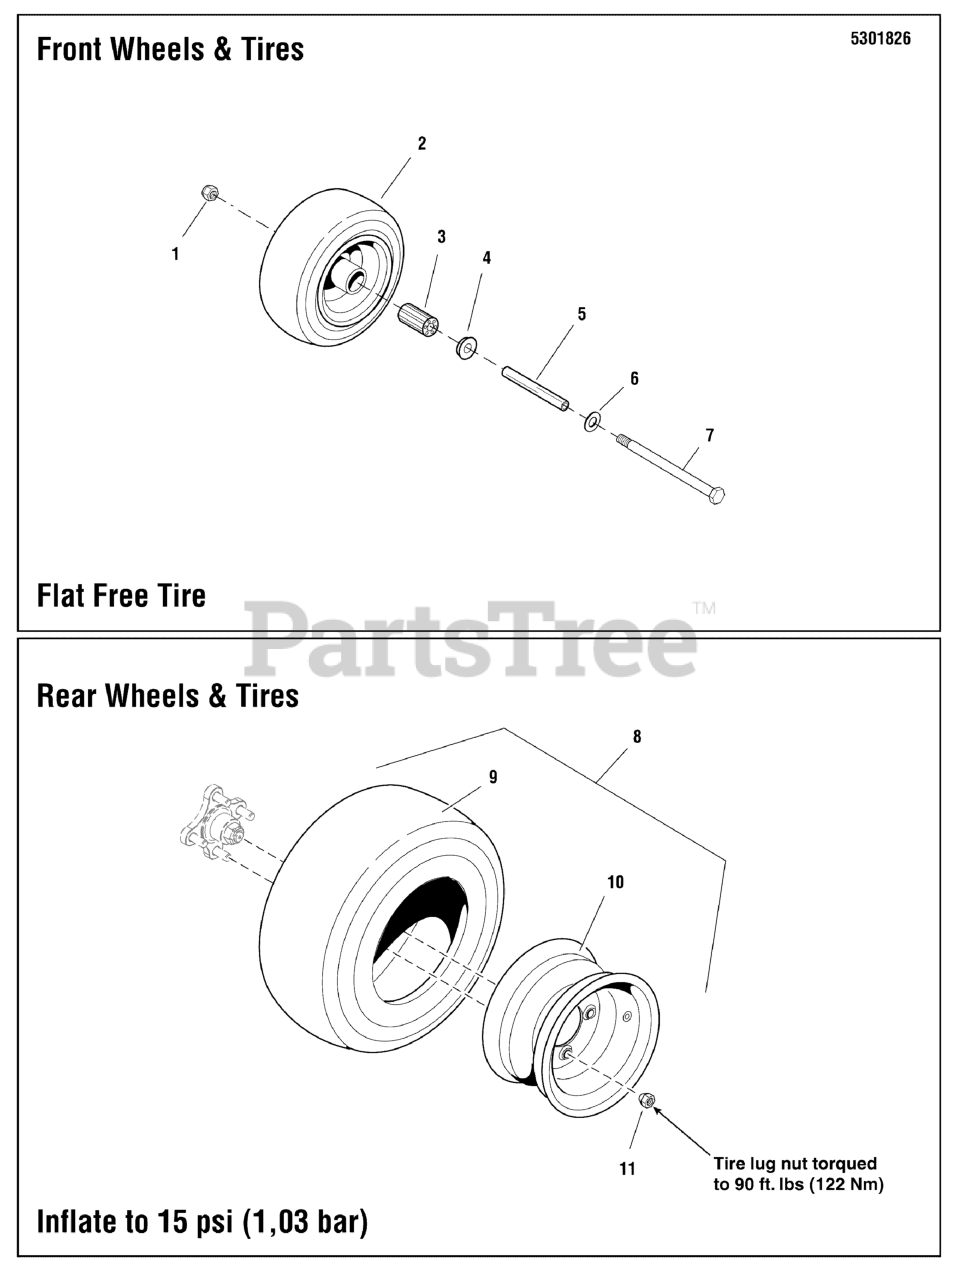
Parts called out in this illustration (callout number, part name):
1	NUT, Hex Flange, Nylock, 1/2-13
2	TIRE ASSM, 11X4.00-5 FLAT FREE
3	BEARING, ROLLER (SV)
4	BEARING, RETAINER (SV)
5	CASTER AXLE DDSH
6	WASHER, 1/2 SAE
7	BOLT, HEX, 1/2-13 X 7, GD 8, YZ
8	TIRE ASSM, 20 X 8 - 10, TURF, 4 BOLT
9	TIRE, REAR, 20X8X10, TURF MASTER (SV)
10	WHEEL, 10X7.00 4/4 SOLID F237 2.625 OS
11	NUT, 1/2-20, FOR WHEEL BOLT, SILVER
